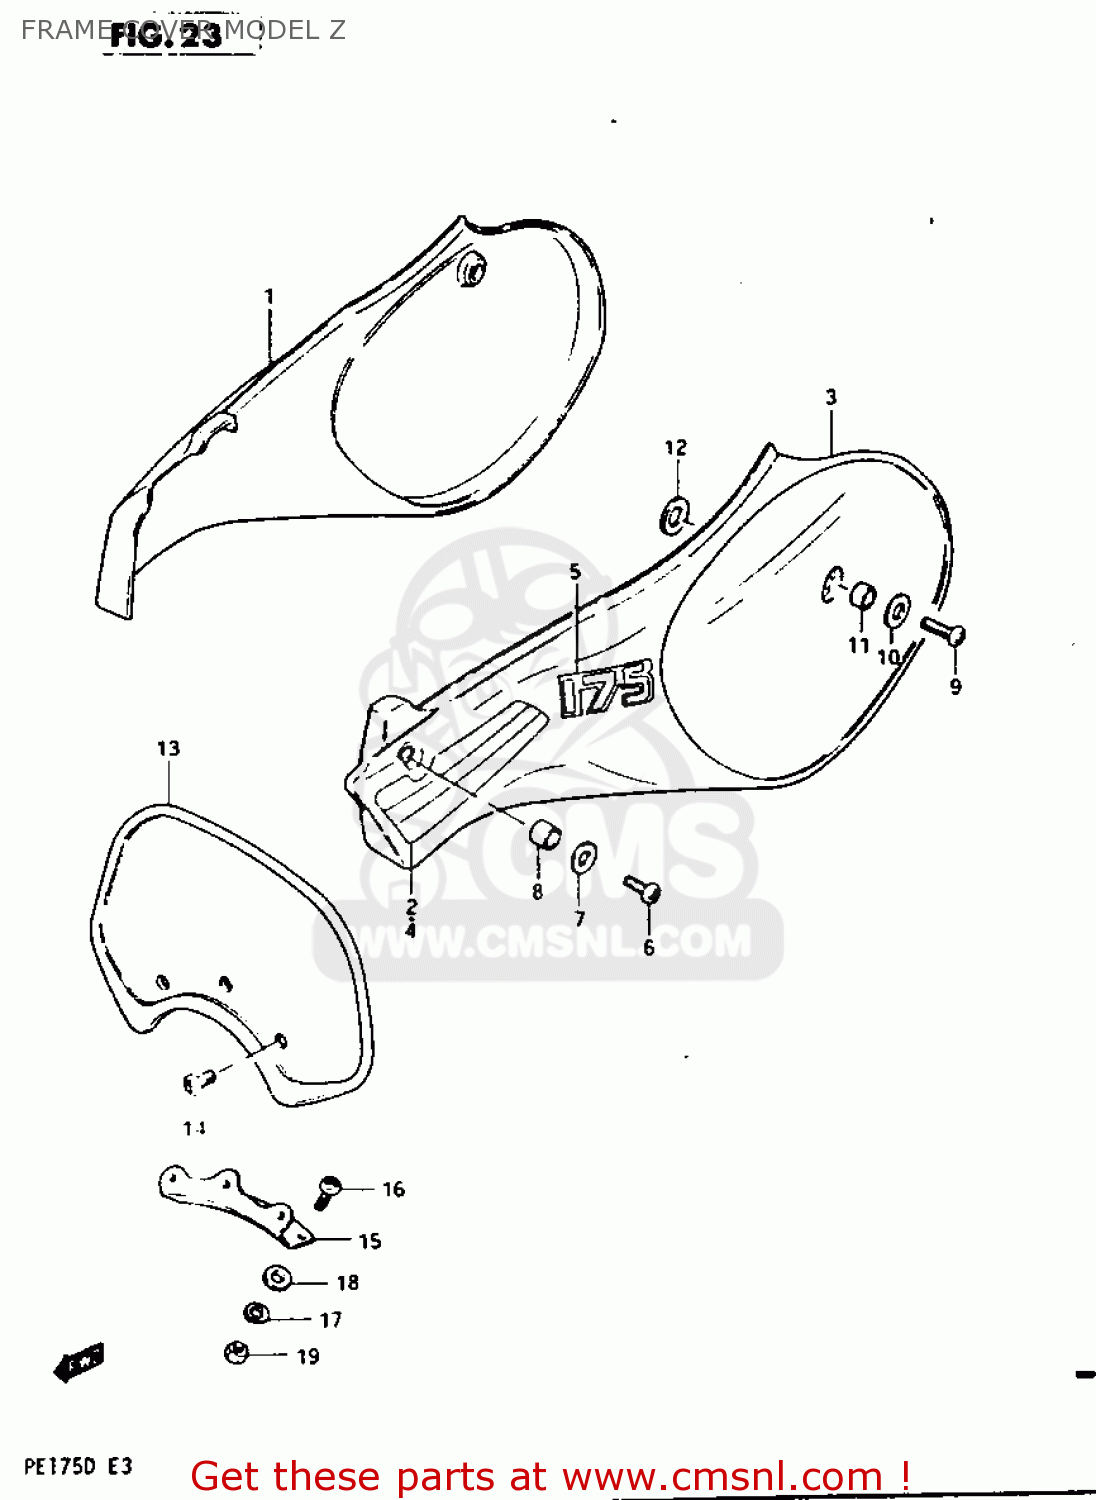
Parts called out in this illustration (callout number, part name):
1	COVER,FRAME,RIGHT
2	TAPE,FRAME COVER,RIGHT
3	COVER,FRAME,LEFT
4	TAPE,FRAME COVER,LEFT
5	EMBLEM
6	SCREW
7	WASHER
8	SPACER (6.1X8X12)
9	SCREW
10	WASHER
11	SPACER
12	GASKET
13	PLATE,FRONT NUMBER
14	SCREW
15	BRACKET FR NUM PLATE
16	SCREW
17	LOCK WASHER
18	WASHER
19	NUT
